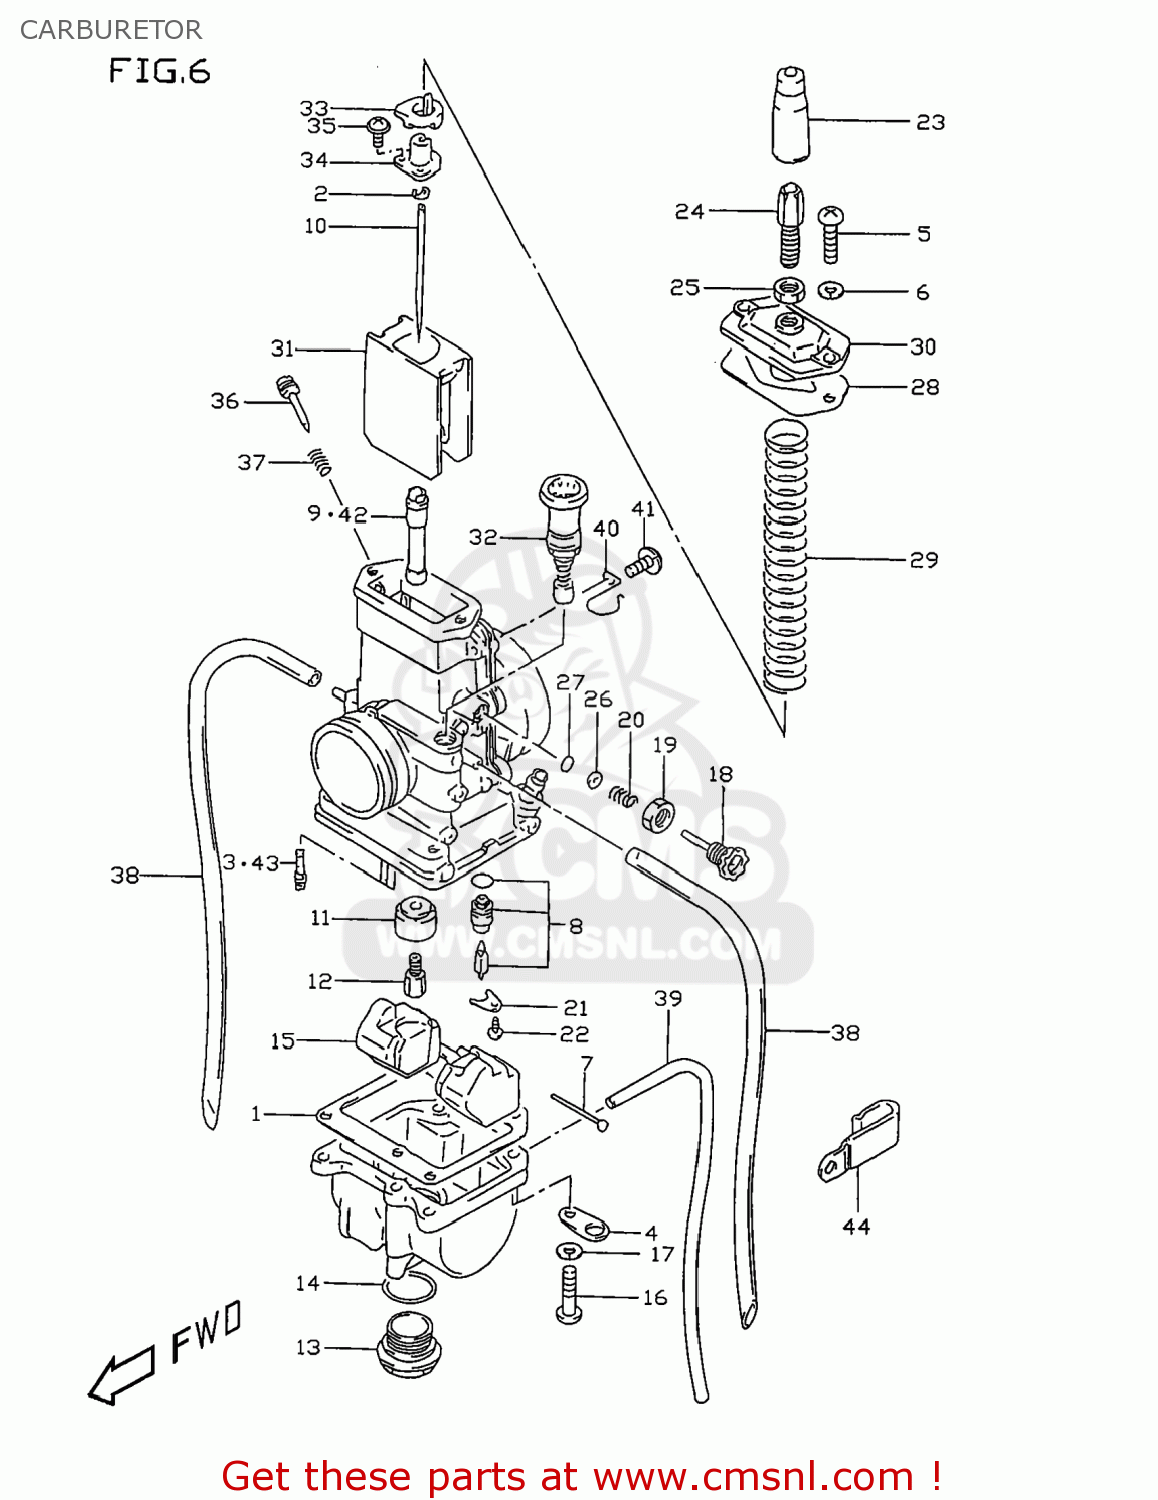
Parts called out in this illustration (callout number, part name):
1	GASKET,FLOAT CAHMBER (NAS)
2	CLIP
3	JET,PILOT(30)
4	PLATE,CARBURETOR
5	SCREW
6	WASHER,LOCK
7	PIN,FLOAT
8	VALVE ASSY,NEEDLE
9	JET,NEEDLE(P-4)
10	NEEDLE,JET(5DP39-4)
11	RING
12	JET,MAIN(210)
13	PLUG
14	O RING
15	FLOAT
16	SCREW
17	WASHER,LOCK
18	ADJUSTER,THROTTLE STOP
19	NUT
20	SPRING
21	PLATE
22	SCREW
23	CAP,CABLE ADJUSTER
24	ADJUSTER,CABLE
25	NUT
26	WASHER
27	O RING
28	GASKET,CARBURETOR TOP (NAS)
29	SPRING
30	CAP,CARBURETOR TOP
31	VALVE,THROTTLE
32	PLUNGER ASSY,STARTER
33	RING
34	JOINT
35	SCREW
36	SCREW,AIR
37	SPRING
38	HOSE(3.5X6.5X600)
39	HOSE(3X5X600)
40	CLIP
41	SCREW
42	JET,NEEDLE,P-2
43	JET,PILOT(25)
44	CLAMP
